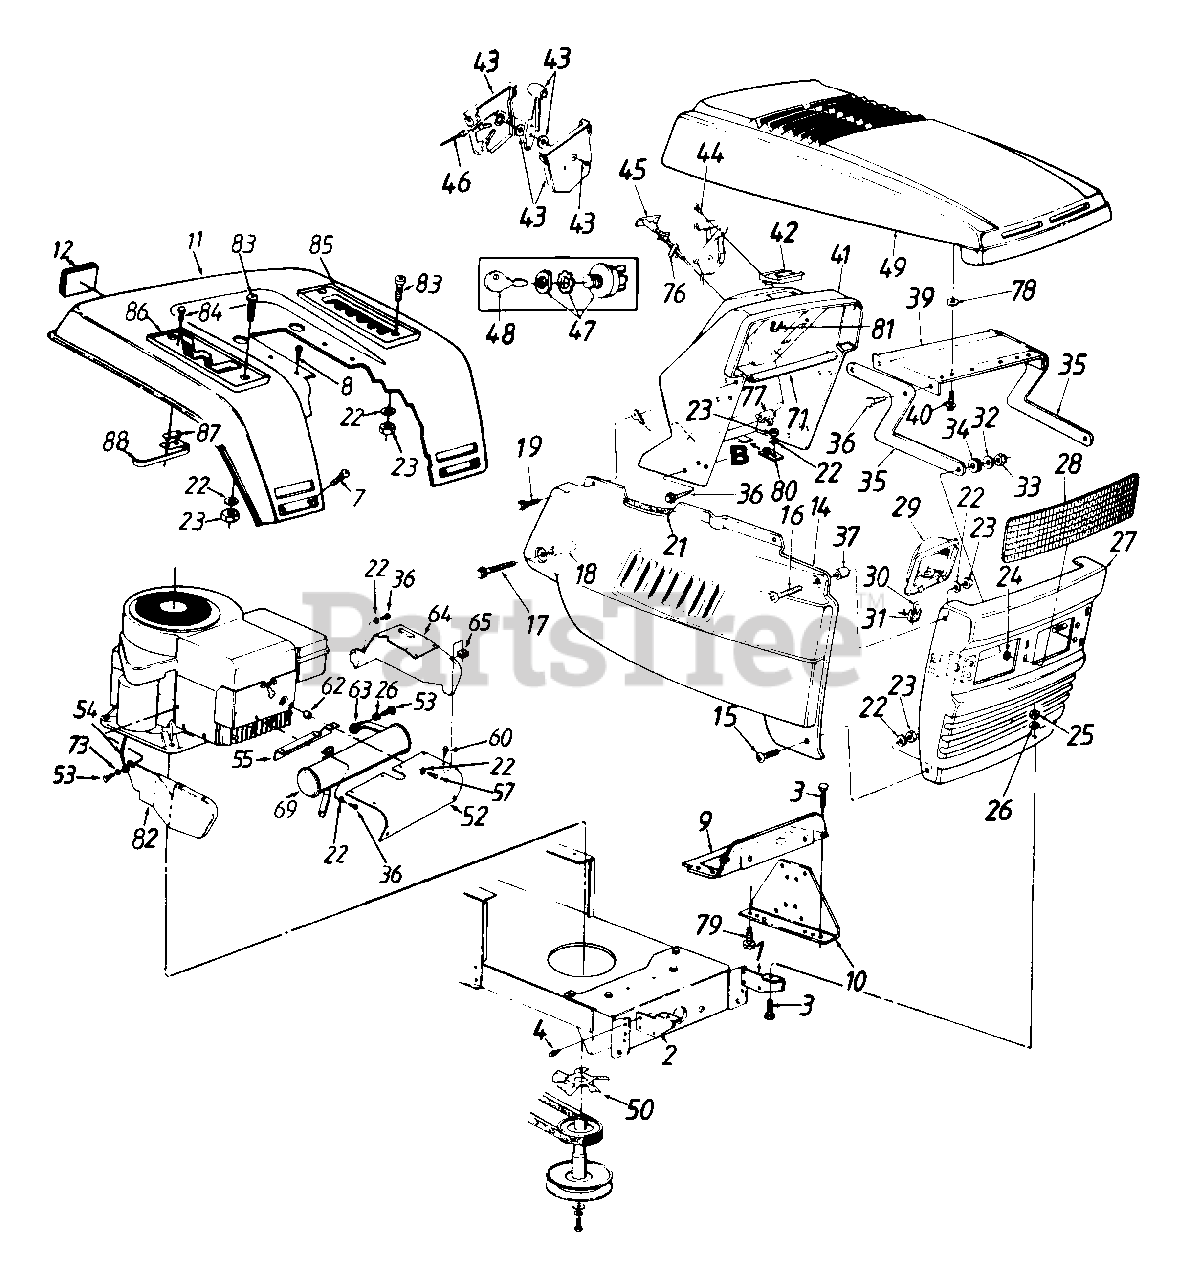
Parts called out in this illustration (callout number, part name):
1	Grille Mtg. Brkt.- L.H.
4	Hex Wash. Hd. Tap Scr. 5/16-18 x .5" Lg.
7	Carriage Bolt 1/4-20 x .5" Lg.
8	Hex Wash. Hd. Tap Scr. 5/16 x .75" Lg.
14	Side Panel - R.H.
16	Truss Mach. Scr. 1/4-20 x 1.0" Lg.
17	Hex Wash. TT-Tap Scr. 1/4-20 x 1.75" Lg.
18	Spacer.26" I.D. x 1.32"
19	Hex Rolling Tap Scr. 1/4-20 x .75" Lg.
21	Trim Strip - 12" Lg.
22	L-Wash, 1/4" I.D.
23	Hex Nut 1/4-20 Thd.
24	Speed Nut 5/16" Thd.
25	Hex Nut 5/16-18 Thd.
26	L-Wash. 5/16" I.D.
29	Headlamp Housing
30	Headlamp
31	Twist Lock Lamp Socket
32	Bell-Wash..345" I.D, x .88"
33	Hex L-Nut 5/16-18 Thd.
34	Rubber Washer
35	Hood Hinge
36	Hex Wash. Hd. B-Tap Scr. 1/4-20 x .5" Lg.
37	Spacer .262" I.D. x .31"
41	Dash
42	Ammeter
43	Throttle Control Box Ass'y.
44	Mach. Scr. #10 x .44" Lg.
45	Choke Control 23" Lg.
46	Throttle Control Wire 18.5" Lg.
47	Ignition Switch
48	Ignition Key
52	Muffler Heat Shield - Fronts
53	Truss Mach. Scr. 5/16-18 x .75" Lg.
54	Ground Wire
55	Heat Shield Bracket
57	Hex Wash. Hd. Tap Scr. 1/4-20 x 1" Lg.
60	Hex Wash. Hd. AB-Tap Scr. #10 x .5" Lg.
62	Spacer .28" I.D. x .5" O.D.
63	Exhaust Gasket
64	Muffler Heat Shield - L.H.
65	Speed Nut #10-24 Thd.
69	Muffler
71	Grille Support Tube
73	External L-Wash. 5/16" I.D.
76	Choke Retainer
77	Light Switch
78	Fl-Wash..406" I.D. x .812" O.D.
79	Hex Bolt 1/4-20 x .62" Lg.
80	Dash Fastening Tab
81	Cable Tie
82	Muffler Heat Shield - R.H.
83	Truss Mach. Scr. 1/4-20 x .75" Lg.
84	Hex Wash. Hd. AB-Tap Scr. #8 x .5" Lg.
85	7-Speed Index Brkt.
86	Forward/Reverse Index Brkt.
87	Insulator Nut Plate
88	Reverse Safety Switch
